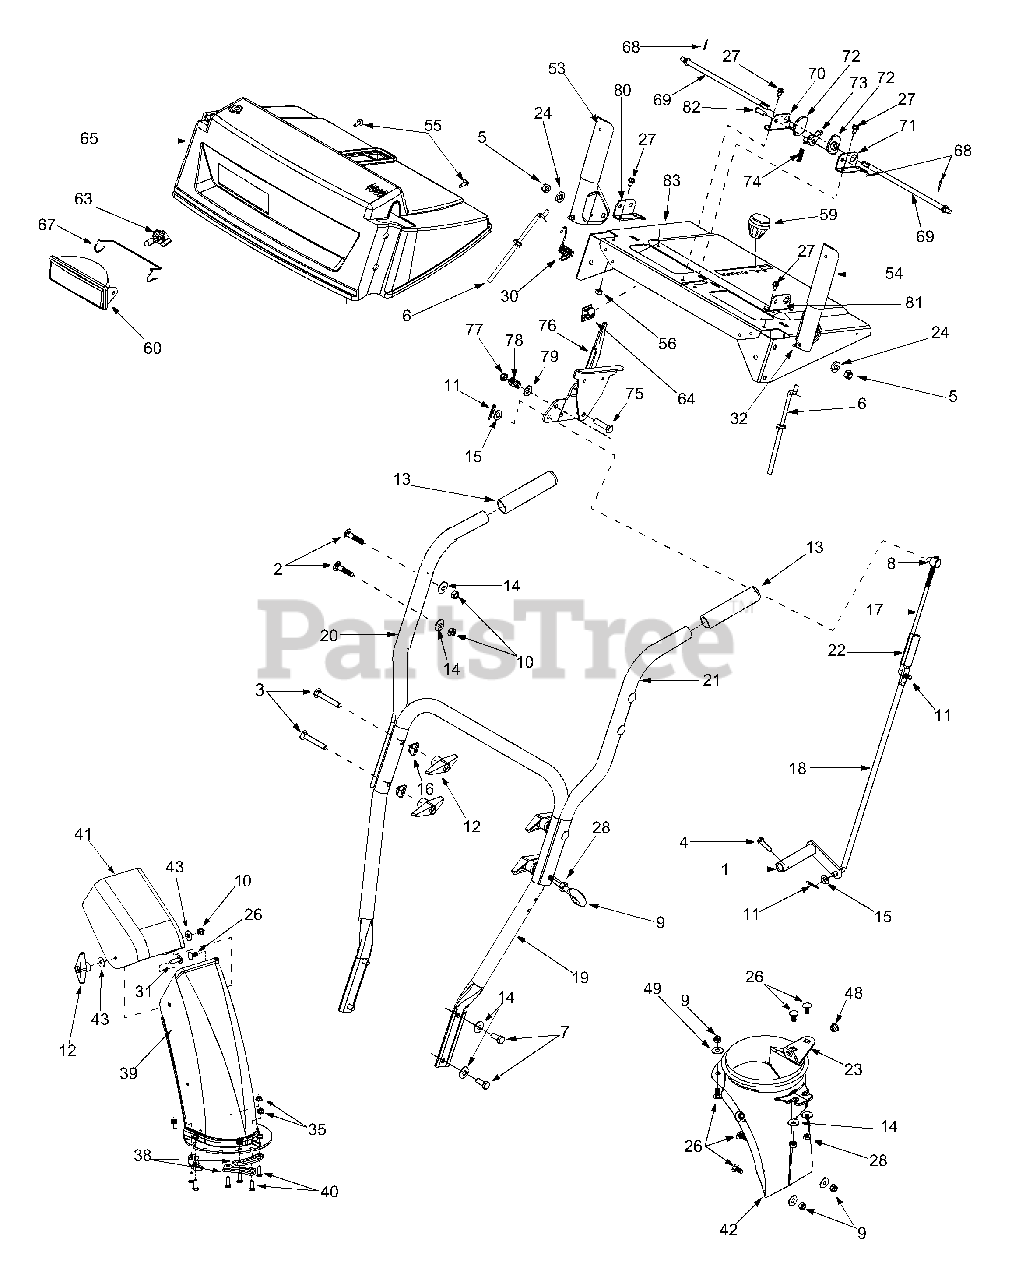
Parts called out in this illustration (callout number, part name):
2	Carriage Bolt 5/16-18 x 1.75"
3	Carriage Bolt 5/16-18 x 2.25"
4	TT Screw 1/4-20 x 1"
5	Hex Lock Nut 5/16-18
6	Z Fitting Cable
7	Hex Screw 5/16-18 x .75"
8	Ferrule
9	Eyebolt
10	Hex Nut 5/16-18
11	Cotter Pin
12	Handle Knob
14	Belleville Washer
15	Flat Washer
16	Saddle Washer
17	Shift Rod: Upper
18	Shift Rod: Lower
24	Washer .72 OD x .135 ID
26	Carriage Bolt: 5.16-18 x .750"
27	TT Screw: 1/4-20 x 0.5"
28	Hex Nut 5/16-18
30	Torsion Spring
31	Carriage Screws 5/16-18 x 1.0
32	Rubber Bumper
35	Hex Flange Lock Nut
38	Chute Flange Keeper
39	Lower Chute
40	Hex Cap Screw 1/4-20 x .75
41	Upper Chute
43	5/16 Washer
48	Plastic Bushing
49	5/16 Washer
53	Handle Assembly RH
54	Handle Assembly LH
55	Special Hex Screw
56	Hex Sems Nut: 1/4-20
59	Shift Knob
60	Lamp Housing
63	Halogen Lamp: 50W, 12V
64	Mounting Clamp
65	Handle Panel
67	Headlight Retainer
68	Cotter Pin: 3/32 x .75
69	Cam Rod
72	Cam Handle Lock
73	Handle Lock Pawl
74	Compression Spring: .36 x 1.0
75	Hex Cap Screw: 3/8-24 x 1.5
78	Comp. Spring: .39 x .6 x .88
79	Bell Washer
82	Clevis Pin
